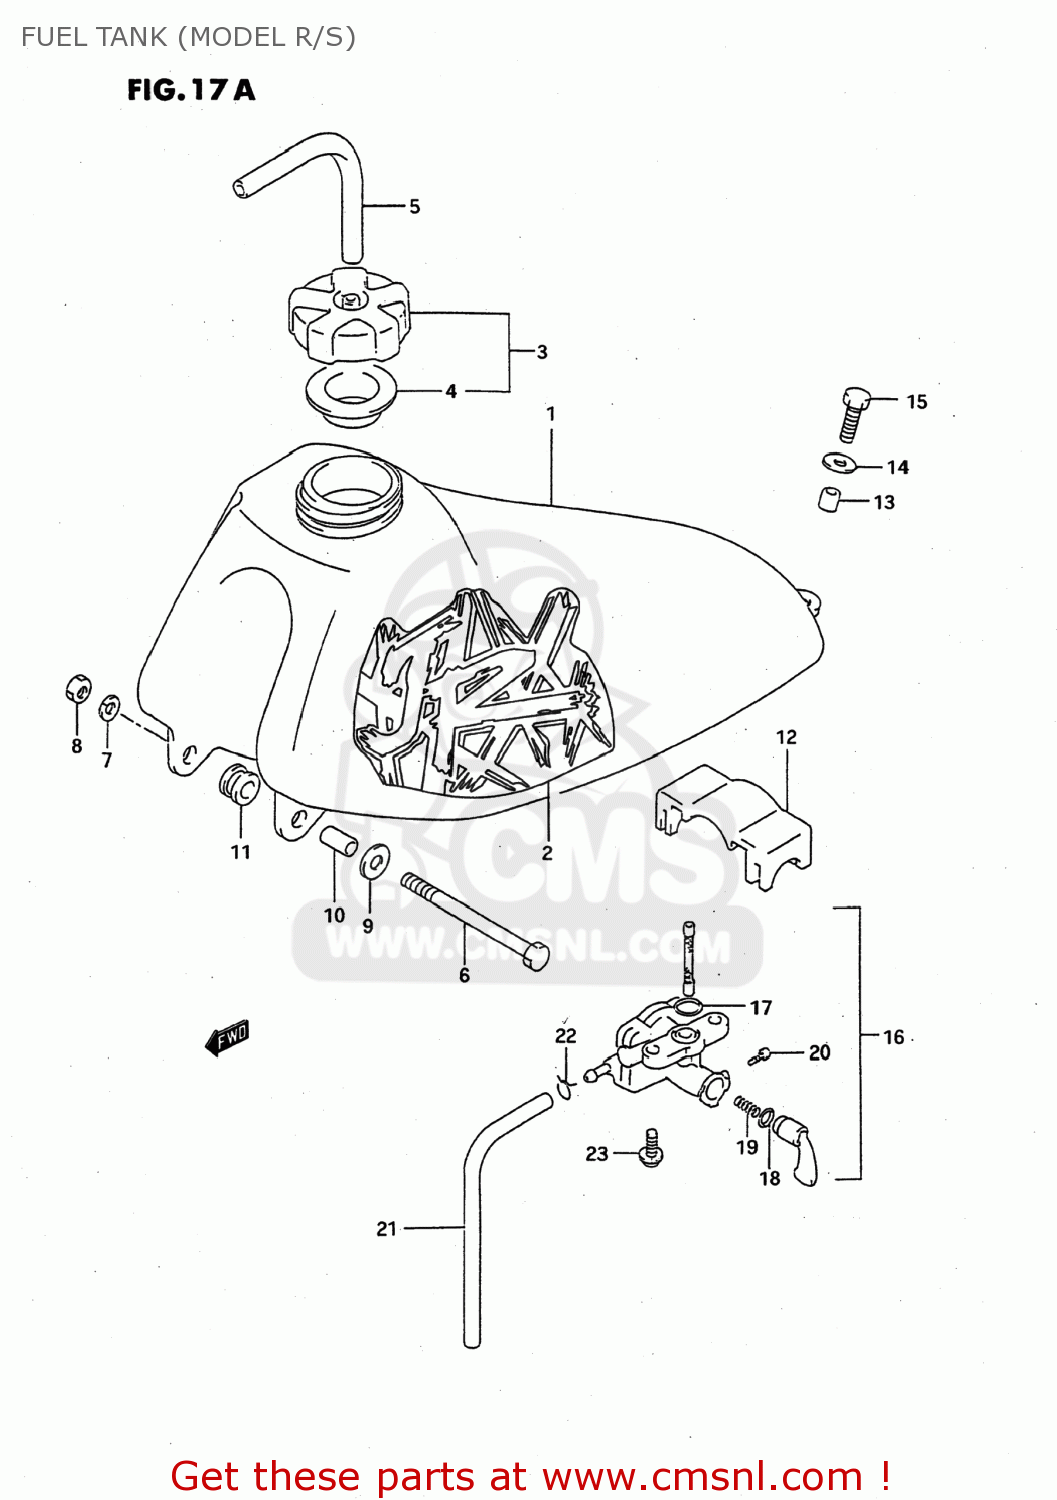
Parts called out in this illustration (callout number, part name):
1	TANK,FUEL
2	EMBLEM,FUEL TANK,LEFT
3	CAP,FUEL TANK FILLER
4	GASKET (NAS)
5	HOSE
6	BOLT, FRONT
7	LOCK WASHER
8	NUT 6MM
9	WASHER(6.5X18X1)
10	SPACER (6.8X10X11.5)
11	CUSHION
12	CUSHION,FUEL TANK UPR
13	SPACER
14	WASHER(6.5X18X1)
15	BOLT
16	COCK ASSY,FUEL
17	O RING
18	O RING,LEVER
19	SPRING,FUEL COCK VALUE
20	SCREW
21	HOSE(5X8.2X600)
22	CLIP
23	SCREW
